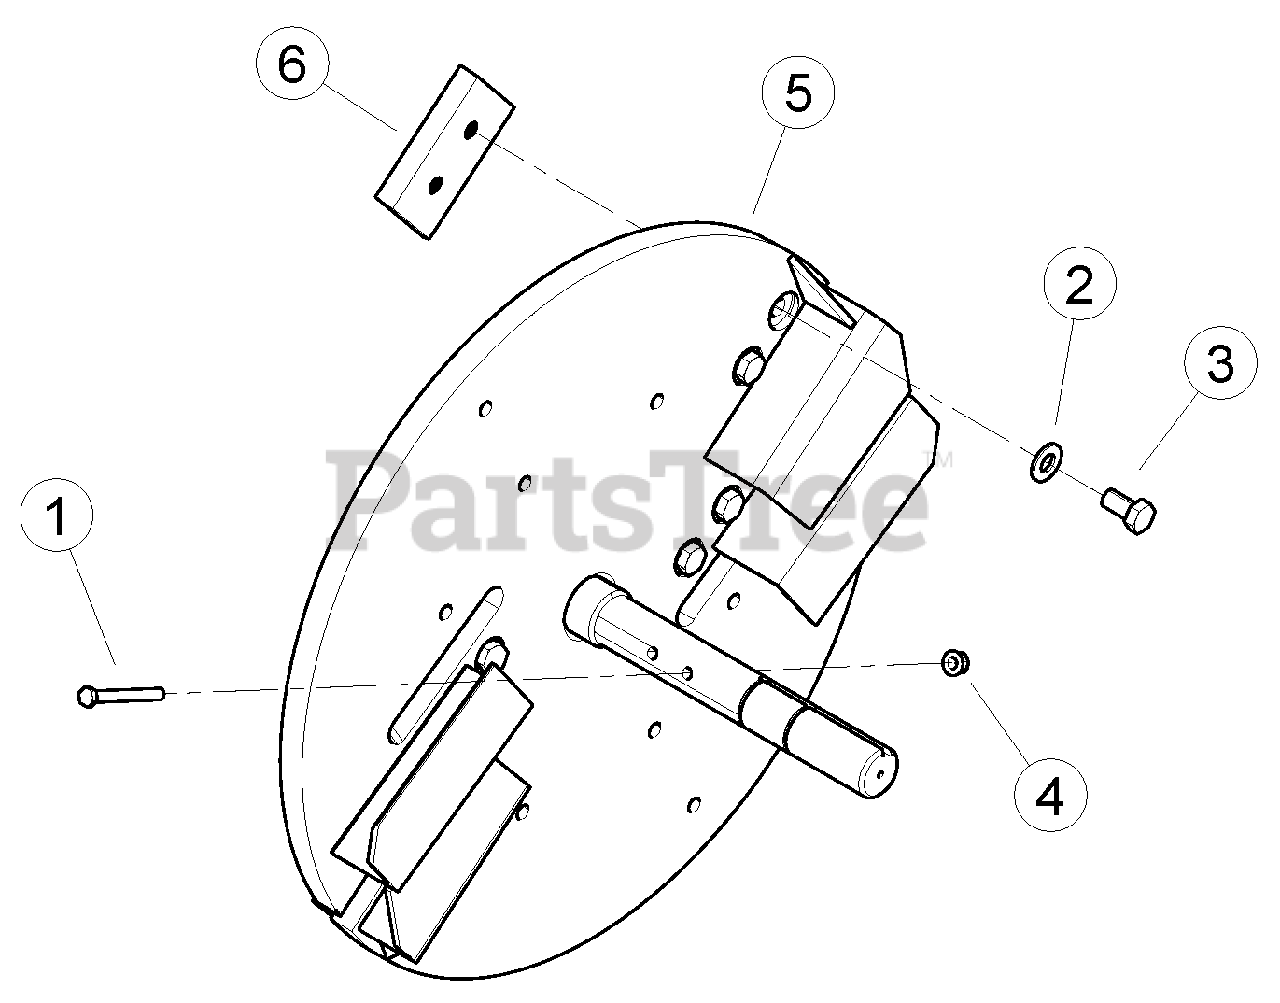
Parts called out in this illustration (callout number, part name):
1	BOLT, 3/8 X 3-1/2 FULL THD ZP GR5
2	WASHER, 5/8 SAE HARDENED
3	BOLT, M16 X 2.0 X 30 HEX HD W/ PATCH
4	NUT, 3/8-16 NYLOCK FLANGE
5	WELDMENT, 6 CHIPPER ROTOR
6	KIT, CHIPPER BLADE
